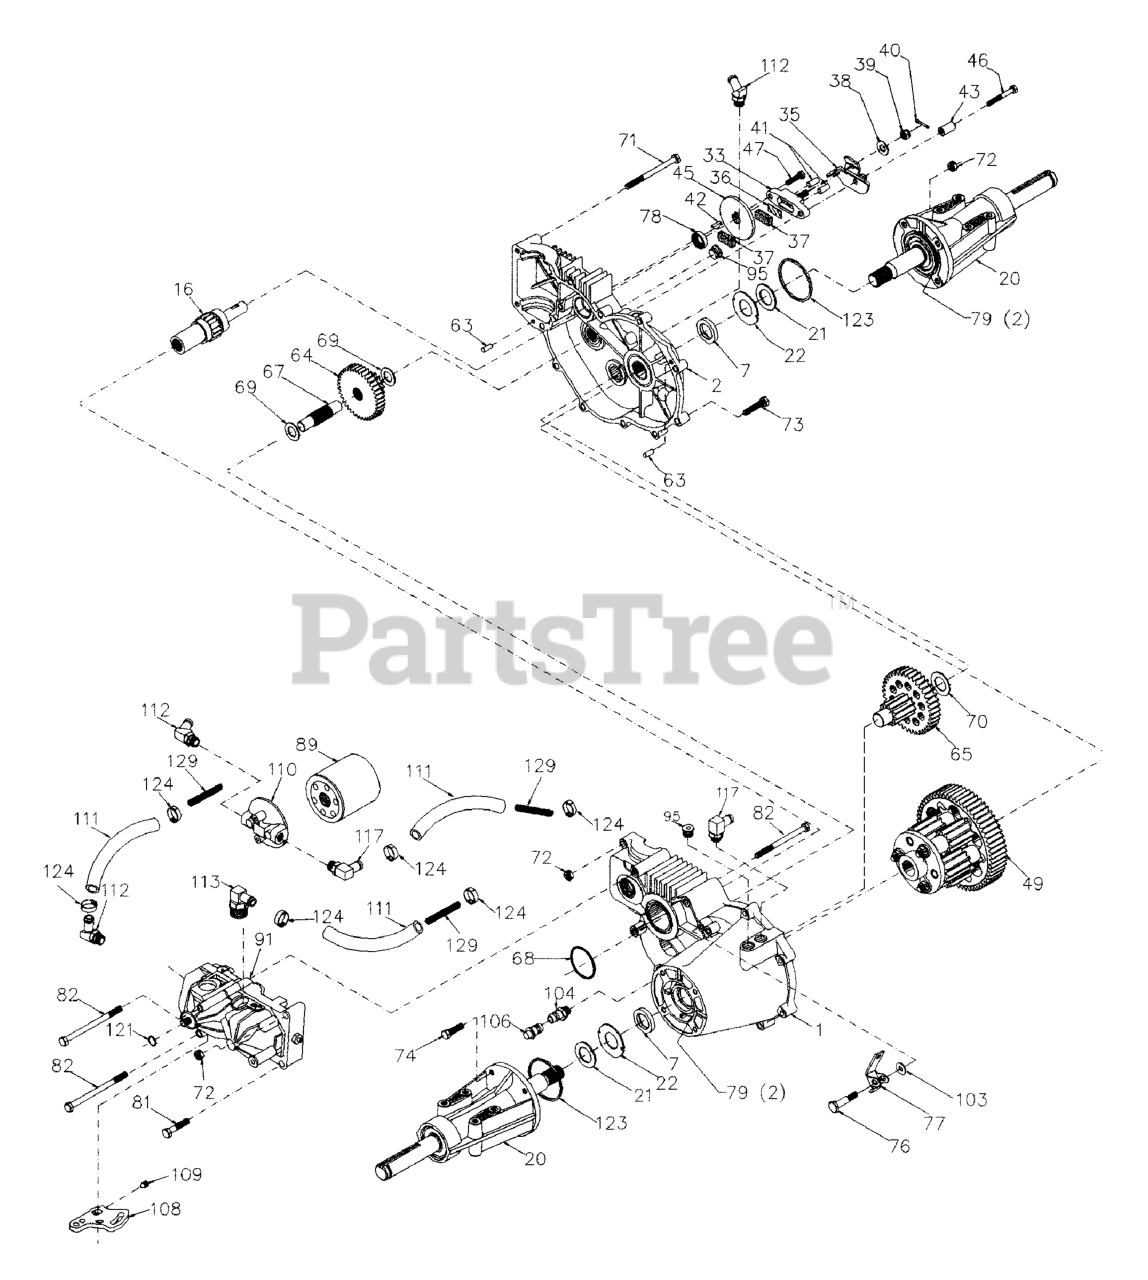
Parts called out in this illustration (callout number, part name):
1	HOUSING.TRANSAXLE.70536
2	ASSEMBLY, RH HOUSING
7	SEAL.OIL.44782.HY (44782)
16	BRAKE SHAFT KIT #62877
20	AXLE.MOUNTING.HORN.70087
21	WASHER 44805
33	BRAKE YOKE ASSEMBLY
35	BRACE ARM 50214
36	PUCK PLATE 44134
37	BRAKE PUCK (44132)
38	WASHER .34X.88X.06.44130
39	CASTLE NUT
40	PIN.COTTER.44101.
41	BRAKE PIN 44127
42	KEY.HIPRO.44143
43	SPACER 50259
45	BRAKE.DISC.44090.
46	BOLT 44276
47	BOLT W/NYLOCK 44433
49	DIFFERENTIAL ASSEMBLY
63	DOWEL.PIN.44757.HYDRO
64	REDUCTION GEAR/14-38 TEETH
65	PINION DR FINAL 70051
67	JACKSHAFT.44779.HYDRO
68	O-RING #44781
69	WASHER.44795.
70	WASHER.44794.HYDRO
71	BOLT HXHD 44827
72	NUT 5/16-18 HEX LOCK 43064
73	BOLT, HEX5/16-18X1-1/2
74	HEX CAP SCREW, 5/16-18X1
76	BOLT.SHOULDER.44785.
77	FREE WHEEL ACTUATING ARM 44786
78	SEAL OIL 70719
79	GREASE (10 OZ TUBE)
82	BOLT 5/16 44820
89	FILTER
91	PUMP.BDU-10L-122
95	PLUG.9005110-5600
103	WASHER 50169
104	CAP, VENT ASSY
106	O-RING KIT 70110
108	ARM CONTROL 45007
109	SCREW.SET.50018
110	FILTER HEAD 50207 HYDRO
113	FITTING, 1/2" BEADED 60 -9/16
117	FITTING.SAE.50589.HYDRO GEAR
123	O-RING 50405
124	CLAMP 50590
129	SPRING.LONG.50667
